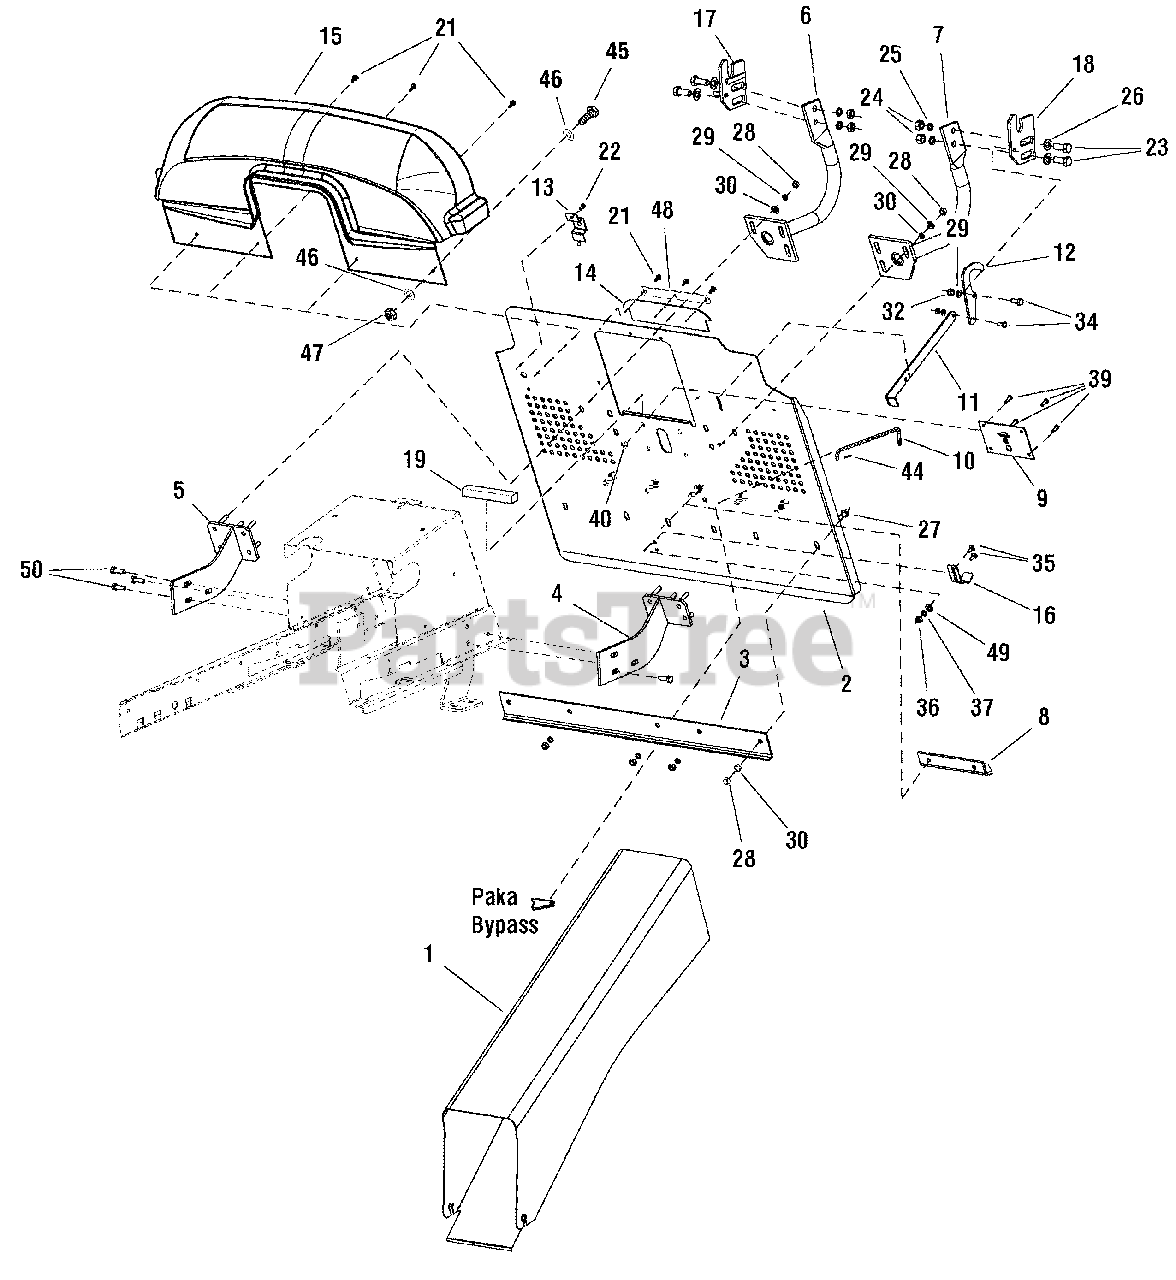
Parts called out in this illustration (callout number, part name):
2	BACK PLATE
4	HOLDER, Back Plate, L.H.
5	HOLDER, Back Plate, R.H.
6	HOLDER, Collector, R.H.
7	HOLDER, Collector, L.H.
9	SWITCH, Full Collector
10	TIE ROD, Bypass 0-8045-260
11	LATCH, Tie Rod
13	COVER, Switch
14	PAD, Rubber 1-1332-332
15	COVER, Plastic
16	SPRING COLLECTOR, Lock
17	HOLDER, Adjustable, Right
18	HOLDER, Adjustable, Left
19	RUBBER EDGE
21	SCREW, ST 5.5 x 19 DIN 7504-K BN1880
22	SCREW, ST 4.2 x 9.5 DIN 7504-K BN1880
23	BOLT, M12 x 30
24	NUT, M12
25	WASHER, 13
26	WASHER, 12
27	BOLT, M8 x 25 DIN 6921 8.8
28	NUT, M8
28	NUT, Flange Lock, M8
29	WASHER, 8.4
30	WASHER, 8
32	NUT, M8
34	BOLT, M8 x 40
35	BOLT, M5 x 16
36	NUT, M5
37	WASHER, 5.3
39	BOLT, M5 x 16
40	NUT, M5
44	SPINDLE, 2 x 20
45	BOLT, M4 x 16
46	WASHER, 4.3
47	NUT, M4
48	PAD, Steel
49	WASHER, 5.3
50	CAPSCREW, Hex Washer Head, Tapitie, 5/16-18 x 5/8
